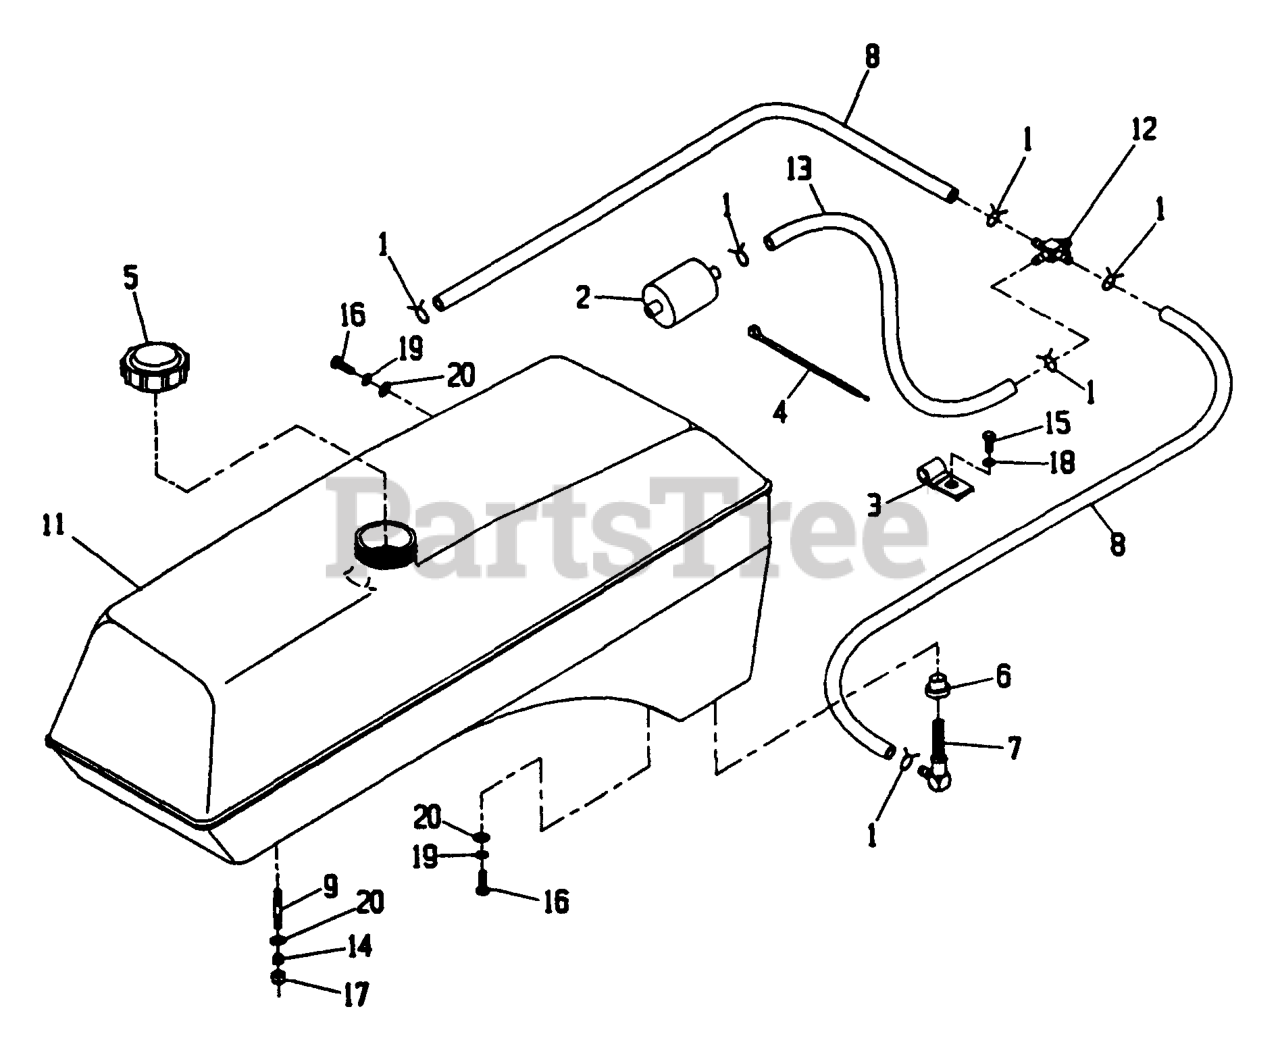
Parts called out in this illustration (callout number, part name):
2	Fuel Filter
3	CLIP-LOOM
4	TIE-PLASTIC
5	CAP-FUEL
7	ELBOW-TANK, FUEL
8	HOSE-FUEL
9	STUD
12	VALVE-FUEL
14	SPRING-TANK, FUEL
18	WASHER-LOCK
19	WASHER-LOCK
